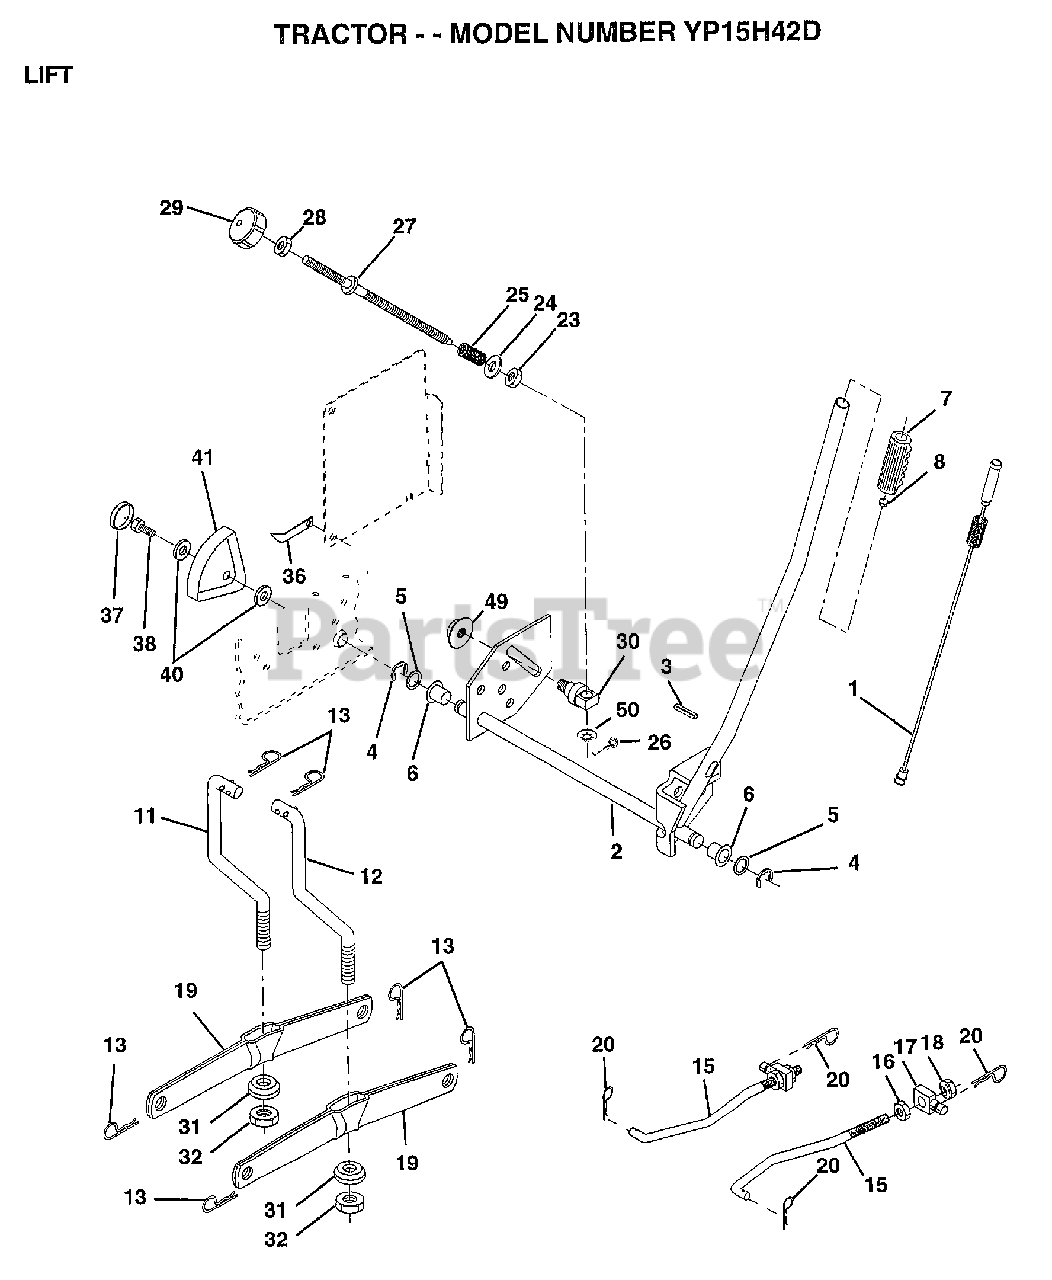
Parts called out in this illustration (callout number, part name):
1	WIRE ASM W.SPRING
2	"SHAFT ASM LIFT,RH"
3	PIN-GROOVE LT
5	WASHER
6	NYLON BEARING
7	GRIP HANDLE
15	LINK.FRONT
16	NUT
17	TRUNION
18	NUT.LK.W/WSH.1/2.
19	ARM SUSP REAR
20	RETAINER SPRING
23	NUT T
24	WASHER
25	SPRING T
28	NUT
29	KNOB INF 3/8-16
30	TRUNNION
31	BEARING PVT LH
32	NUT.CROWNLOCK.3/8
36	POINTER-INDICAT
37	"PLUG,HOLE"
38	SCREW
40	WASHER
41	HEIGHT INDICATOR
49	NUT.HXFLG.LOCK.
50	NUT PUSH M
